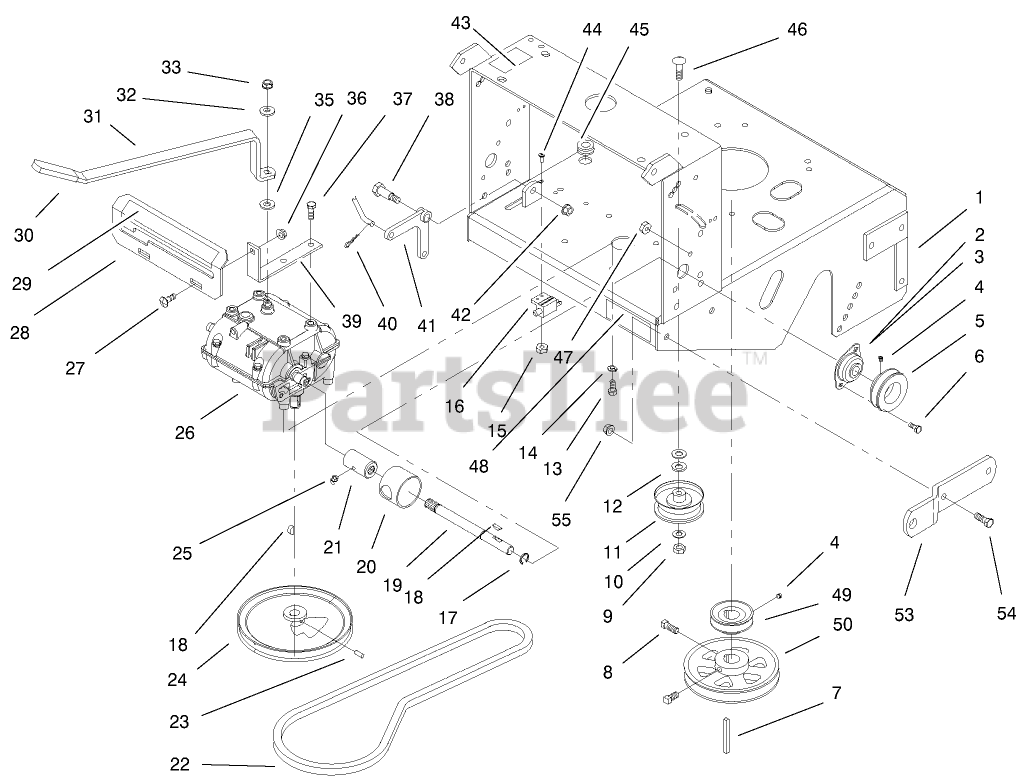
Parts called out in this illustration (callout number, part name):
1	Rear Deck
2	Bearing
3	Flange
4	Screw-Set
5	Sheave,Wheel Drive
6	SCREW-HH
7	Key
8	SCREW-SET, SQH
9	NUT-LOCK, NI
10	WASHER-FLAT
11	Idler Pulley
12	WASHER-FLAT
13	SCREW-HH
14	WASHER-LOCK
15	NUT-LOCK, NI
16	Switch-Seat
17	Ring-Retaining
18	Key
19	Output Shaft
20	GUARD-COUPLER
21	Coupling
22	Belt-Trans Drive
23	Screw-Set
24	Sheave
25	FITTING-GREASE
26	Transmission
27	BOLT-CARR
28	Shifter Plate
29	DECAL-SPEED, GROUND
30	Grip
31	LEVER-SHIFT
32	WASHER-BELLEVILLE
33	NUT-LOCK
35	Washer
36	NUT-HF
37	SCREW-HWH
38	Bolt-Shoulder
39	Leg-Shifter Lever
40	PIN-COTTER
41	Bell Crank
42	NUT-HHF, WHIZ
43	DECAL-SHUT OFF, FUEL
44	Screw
45	Grommet-Fuel Line
46	Bolt-CARR
47	NUT-LOCK, NI
48	DECAL-CAUTION
49	Sheave
50	Pulley-Blade Drive
53	Hitch Bracket
54	SCREW-HH
55	NUT-HHF, WHIZ
